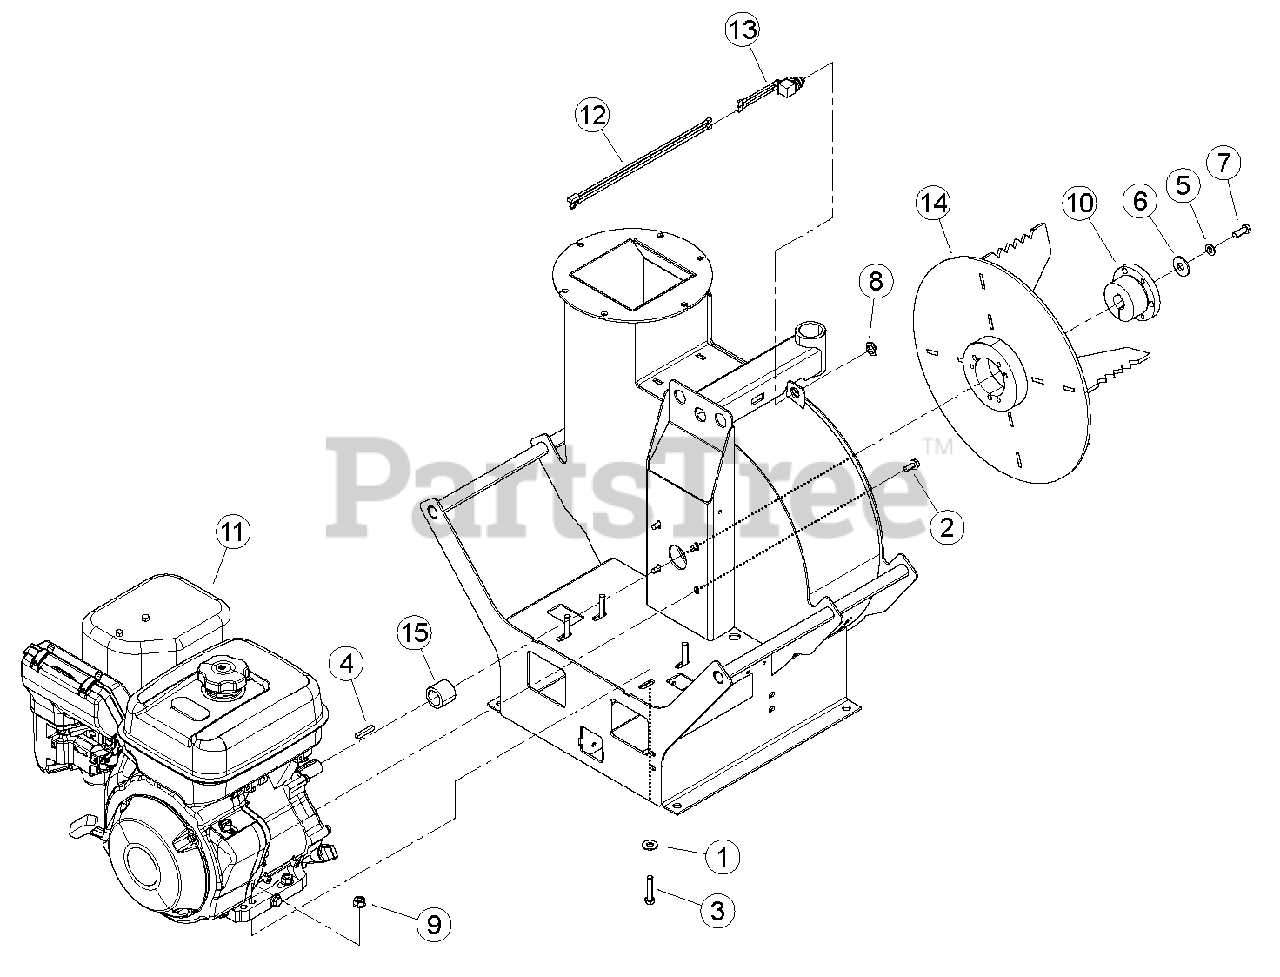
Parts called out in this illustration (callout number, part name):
1	WASHER, 3/8 FLAT
2	BOLT, 5/16 X 3/4 SERRATED FLANGE NF
3	BOLT, 3/8 X 1-3/4 GR5 HCS ZP
4	KEY, 1/4 SQ X 1-1/2 LG PLAIN
5	WASHER, M10 FLAT (10.5 X 20 X 2) YZP
6	WASHER, 1/2USS G8 ZP
7	BOLT, 3/8 X 1" NF GR8 ZP HHCS
8	NUT, 5/8-32 JAM
9	NUT, 3/8-16 NYLOCK FLANGE
10	BUSHING, 1" SK
11	ENGINE, SUBARU 404CC EX40 (FOR SERVICE SEE ENGINE OWNER'S MANUAL OR YOUR NEAREST SUBARU INDUSTRIAL ENGINE DEALER)
12	HARNESS, SUBARU ENGINE KILL SWITCH
13	ASSEMBLY, SEALED SWITCH NORMALLY CLOSED
14	WELDMENT, FAN "BEAR CLAW"
15	SPACER, 1.50 X 1.25 X 7/32 WALL
